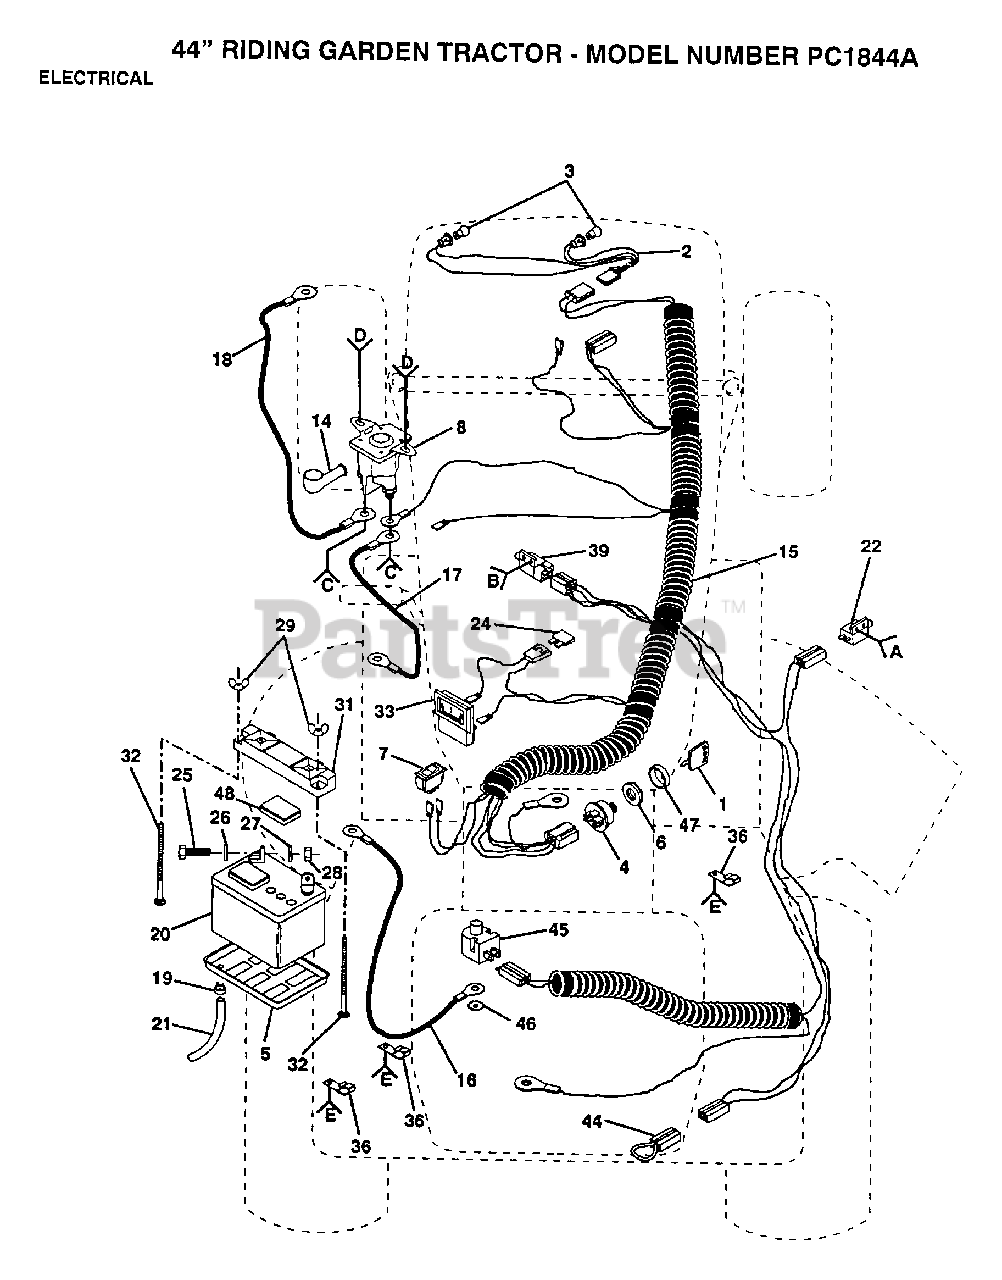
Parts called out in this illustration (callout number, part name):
1	KEY
2	HARNESS T
5	"TRAY T, BATTERY"
7	SWITCH LT
10	NUT
11	BOLT
13	NUT
15	HARNESS
16	"CABLE T, BATTERY"
17	CABLE LT
18	CABLE T
19	HOSE CLAMP T
22	SWITCH-INTER. GT
23	SCREW
24	FUSE HYT
25	BOLT LT
26	WASHER
27	LOCKWASHER
32	BOLT
36	CLIPT
39	SWITCH INTERLOCKT
42	SCREW
43	"NUT,KEPS"
45	SWITCH SEAT
46	LOCKWASHER
48	"CAP,BATTERY "
